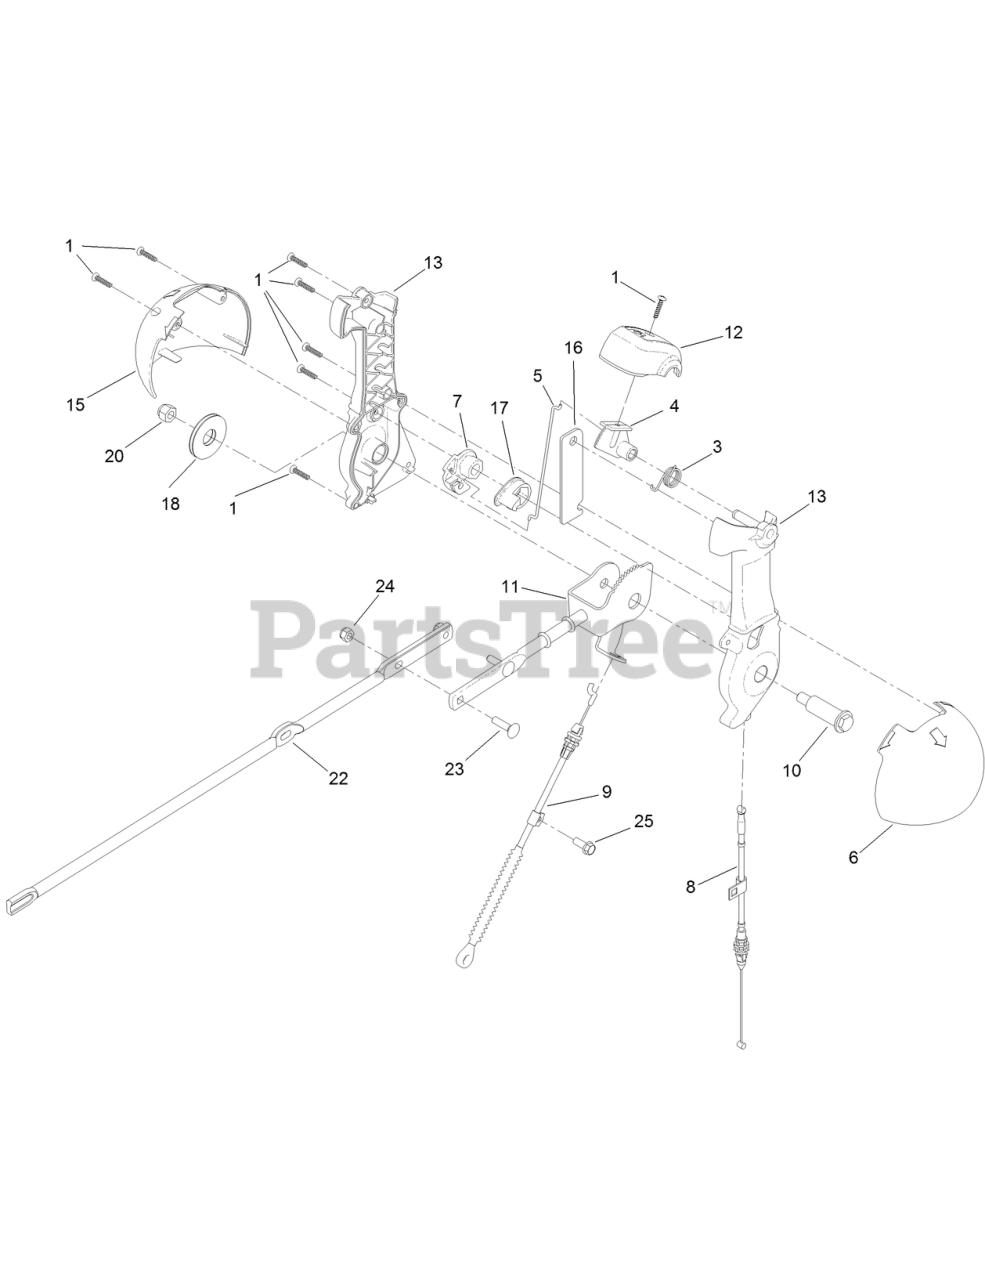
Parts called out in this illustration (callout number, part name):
1	SCREW-PPH
3	SPRING-TORSION
4	TRIGGER-LATCH
5	LINK-LATCH
6	GLOBE-QUICKSTICK, LH
7	LEVER-CABLE, DEFLECTOR
8	CABLE-RELEASE, CHUTE
9	CABLE-CONTROL, DEFLECTOR
10	SCREW-SHOULDER, HWH
11	ROD-CONTROL, CHUTE
12	CAP-LEVER
15	GLOBE-QUICKSTICK, RH
16	PLATE-STIFFNER
17	PAWL-LATCH
18	WASHER-FRICTION, COMPOSITE
20	NUT-HEX
22	ROD-CHUTE
23	BOLT-CARR
24	NUT-HEX
25	SCREW-HWH
